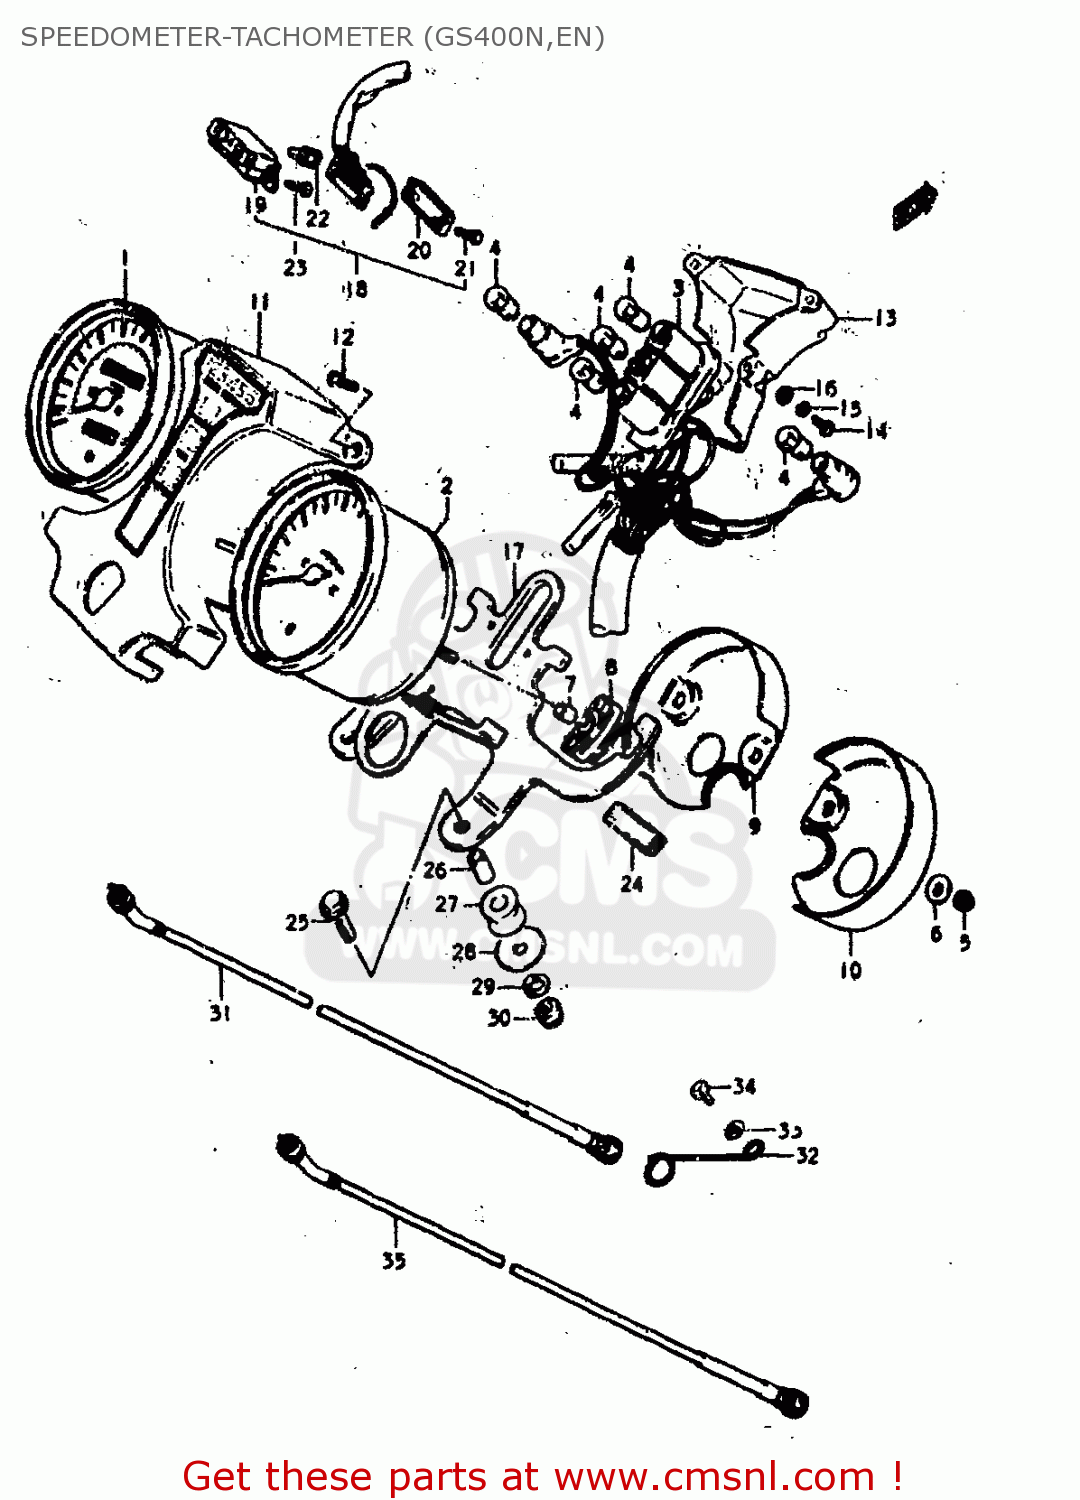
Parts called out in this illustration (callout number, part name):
1	SPEEDOMETER
2	TACHOMETER
3	SOCKET,METER
4	BULB(12V3.4W,STANLEY,A72A)
5	NUT
6	WASHER (5.5X16X1.2)
7	SPACER
8	CUSHION,METER
9	UNDER COVER,SPEEDOMETER
10	UNDER COVER,TACHOMETER
11	CASE,PILOT BULB
12	SCREW
13	COVER,PILOT BULB CASE
14	SCREW(4X16)
15	WASHER,PILOT UNDER CASE
16	WASHER
17	BRACKET,METER
18	INDICATOR ASSEMBLY,GEAR POSITION
19	CASE,GEAR INDICATOR
20	COVER,LWR
21	SCREW,GEAR INDICATOR
22	BULB(14V1.12W)
23	SCREW
24	CUSHION,METER
25	BOLT
26	SPACER (6.1X8X15.5)
27	CUSHION
28	WASHER
29	LOCK WASHER
30	NUT
31	CABLE ASSEMBLY,SPEEDOMETER
32	GUIDE,SPEEDOMETER CABLE
33	WASHER 6MM
34	BOLT, UPPER
35	CABLE ASSEMBLY,TACHOMETER
